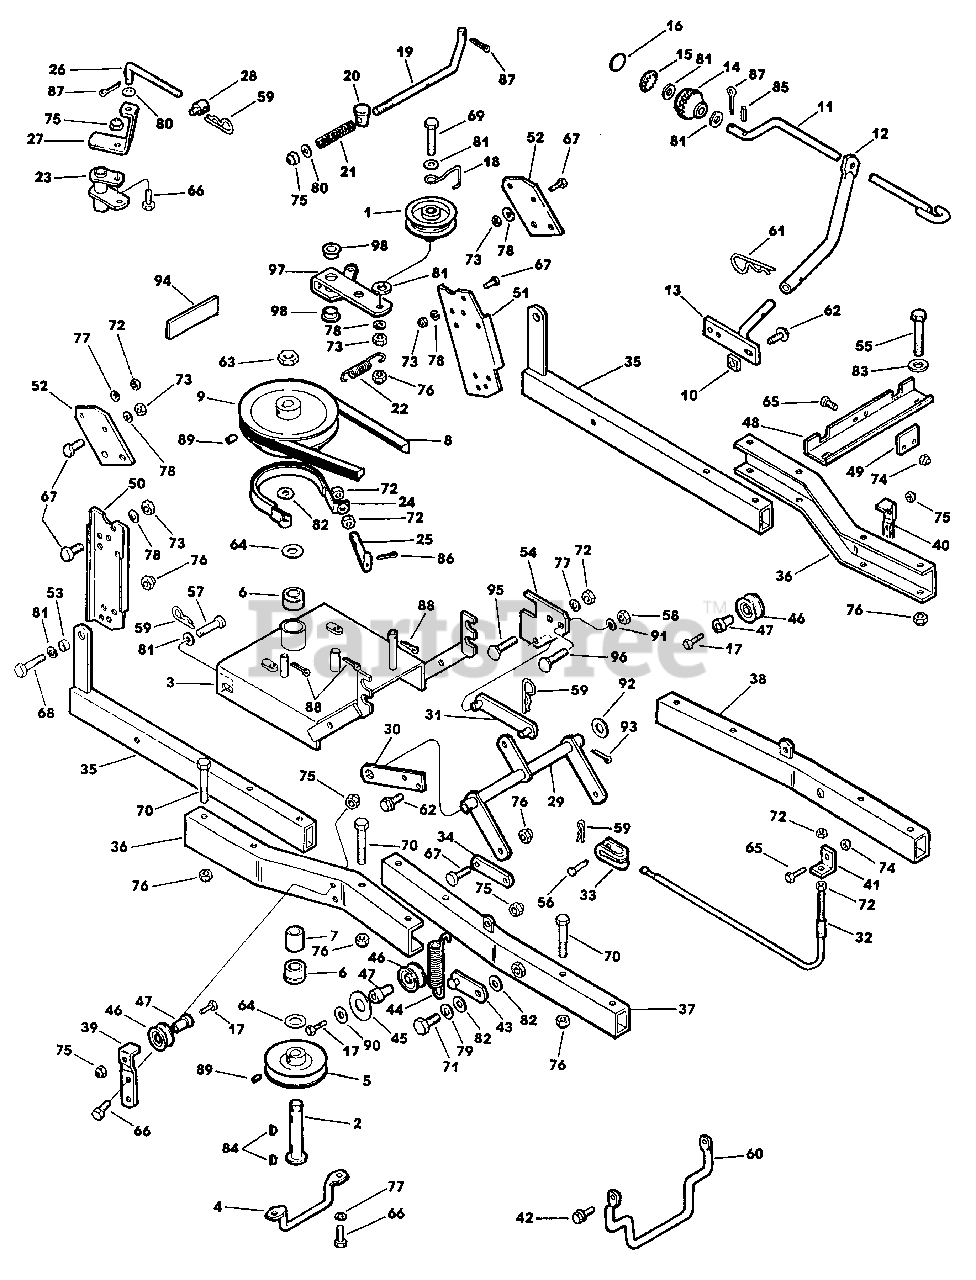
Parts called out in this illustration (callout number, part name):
1	Idler Pulley
2	Jackshaft
3	Pulley Support
4	Belt Guard
5	Pulley
6	Bearing w/Snap Ring
7	Spacer
8	V-Belt (Primary)
9	Pulley And Brake Drum
10	Spacer
11	Chute Control Crank
12	Tube-Chute Control Support
13	Support-Chute Control
14	Knob
15	Plug Button & Decal Ass'y
16	Decal-Discharge Control
17	Cap Screw, Hex Hd
18	Belt Finger
19	Clutch Rod
20	Pin-Clutch Rod
21	Spring-Clutch Rod
22	Spring-Brake
23	Clutch Arm
24	Brake Assembly w/Lining
25	Brake Rod
26	Over Center Rod
27	Extension Arm (Yard Tractor Only)
28	Trunnion
29	Bellcrank Ass'y. (For All Gear Drive Tractors & Hydro Tractors With Side Air Screen.)
30	Lift Support Arm
31	Lift Link
32	Lift Cable
33	Lift Clevis
34	Cable Extension-4" (Yard Tractor)
35	Rear Frame
36	Frame Connecting Channel
37	Front Frame Weldment-R.H
38	Front Frame Weldment-L.H
39	Plate, Cable Roller Mounting-R.H
40	Plate, Cable Roller Mounting-L.H
41	Bracket, Cable Adjustment
42	Thread Forming Screw, Hex Hd
43	Spring Adjustment Arm
44	Assist Spring
45	Washer
46	Cable Roller
47	Spacer-Roller
48	Frame Stop
49	Frame Stop Extension (Yard Tractor)
50	Mounting Bracket-R.H. (Yard Tractor)
51	Mounting Bracket-L.H. (Yard Tractor)
52	Hanger Plate (Lawn Tractor)
53	Spacer
54	Lift Arm (Lawn Tractor)
55	Cap Screw, Hex Hd
56	Clevis Pin
57	Clevis Pin
58	Nut, Hex
59	Spring clip
60	Belt Guide, Engine Pulley (Lawn Tractor)
61	Spring Clip
62	Thread Forming Screw, Hex Hd
63	Nut, Hex Center Lock
64	Thrust Washer
65	Cap Screw, Hex Hd
66	Cap Screw, Hex Hd
67	Cap Screw, Hex Hd
68	Cap Screw, Hex Hd
69	Cap Screw, Hex Hd
70	Cap Screw, Hex Hd
71	Cap Screw, Hex Hd
72	Nut, Hex
73	Nut, Hex
74	Nut, Hex Cone Lock
75	Nut, Hex Cone Lock
76	Nut, Hex Cone Lock
77	Washer, Spring Lock
78	Washer, Spring Lock
79	Washer, Spring Lock
80	Washer, Flat
81	Washer, Flat
82	Washer, Flat
83	Washer, Flat
84	Key, Woodruff
85	Roll Pin
86	Cotter Pin
87	Cotter Pin
88	Cotter Pin
89	Setscrew, Hex Socket Hd
90	Washer, Flat
91	Washer, Spring Lock
92	Washer
93	Cotter Pin
94	Reflector
95	Bolt, Carriage
96	Bolt, Carriage
97	Chute Idler Arm Ass'y. w/Bushings
98	Bushing
